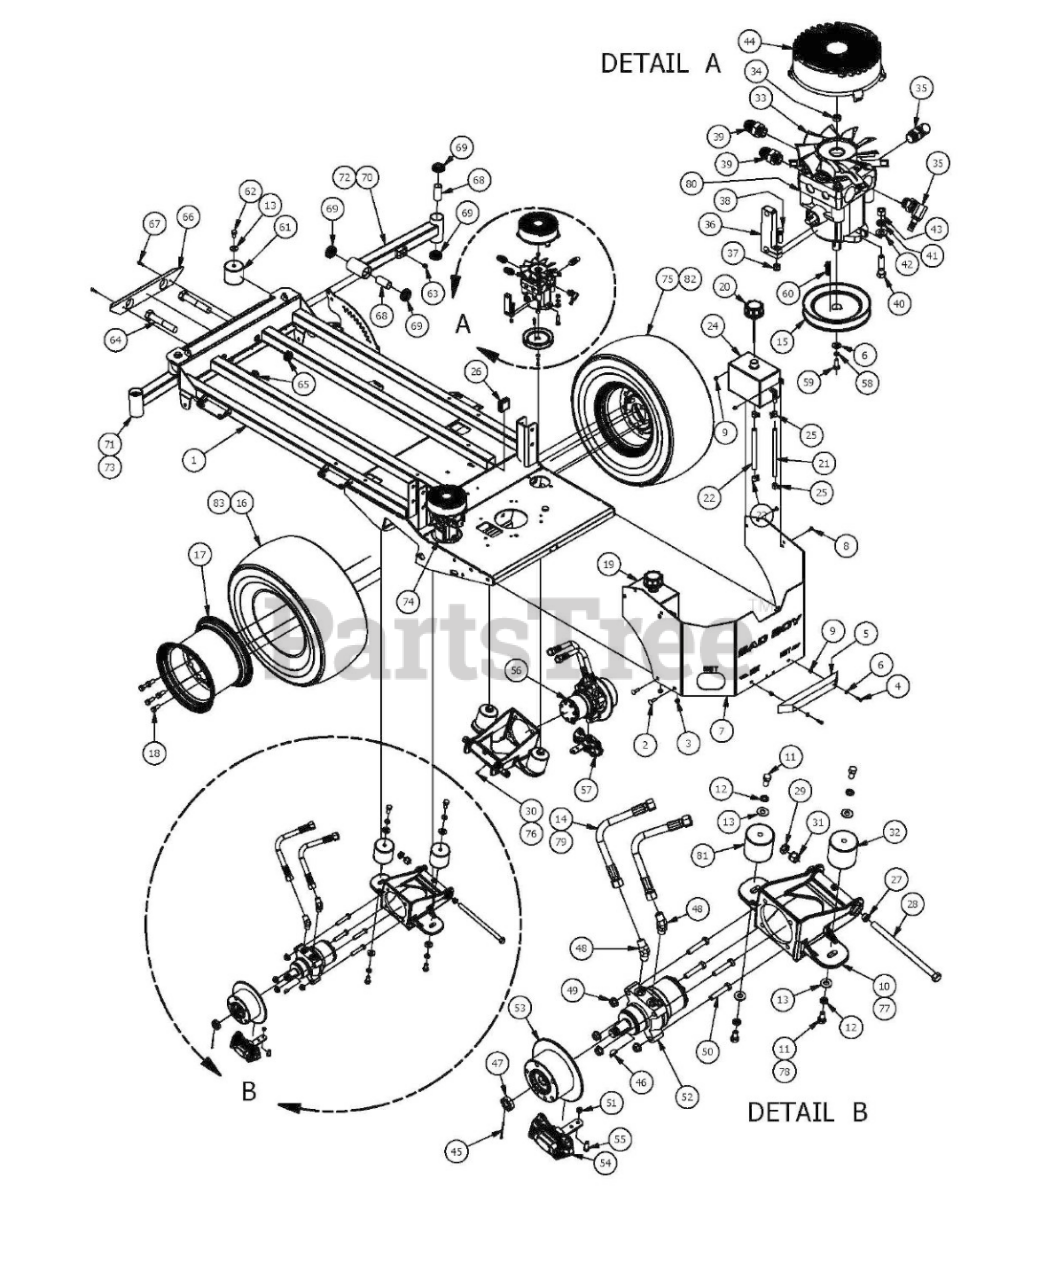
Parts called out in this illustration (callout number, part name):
1	2017 XP Frame
2	3/8" x 1 1/4" Carriage Bolt
3	3/8 Nylock Nut
4	1/4-20 x 1-1/4 GR 5 Hex Bolt
5	14" Rubber Bumper
6	1/4" Flat Washer
7	Outlaw Rear Plate
8	1/4" x 3/4" Carriage Bolt
9	1/4-20 Nylon Insert flange Nut
10	60 Suspension kit Wheel Motor
11	1/2" x 1" Hex Bolt
12	1/2" Lock Washer
13	1/2" Washer (Grade 8)
14	18" hose Assembly W/forged 45 Degr
15	5" Pump Pulley
16	24 x 12-12 Tire Pro Maxxis
17	12x12" Black Wheel For 2015 Outlaw
18	1/2-20 x 1-1/2 Lug Bolts Zinc
19	Outlaw Hydraulic Tank Left
20	Hydraulic Tank Cap W/Dipstick
21	3/8" Clear Hose
22	1/2 Clear Braded Hose Priced/Foot
23	1/2 Hose Clamp
24	Outlaw Hydraulic Tank Right
25	3/8" Hose Clamp
26	2X2 Frame Plug
27	Flange Bushing for Deck Arm - Upper
28	5/8"x10" Hex Bolt (Grades)
29	5/8" Nylock (1/2 Jam)
30	1/4" Drive in Grease Fitting (72" Suspension Kit
31	5/8 Std NC Nylock Nut
32	Vibration Mount-Green Dot
33	Hydraulic Fan
35	3/8" X 9/16"-18 ORB Male Fitting (S,A-2 P-4)
37	1/4" Nylock Nut
38	1/4-20 x 1 GR 5 hex bolt zinc
39	Hydraulic Pump Fitting 6400-10
40	3/8" x 1 1/2" Hex Bolt
41	3/8" Lock Washer
42	3/8" Flat Washer
43	3/8" Hex Nut
44	Fan Guard 6" Fits wheel Motor Pumps
45	1/8x2-1/4 cotter pin Zinc
46	Woodruff Key
47	1" Castle Nut for Wheel Motor
48	45 Degree Fitting 31704-10-10
49	1/2" Flange Nut
50	1/2" x 2 1/2" Hex Bolt
51	5/16-18 Nylock Insert Locknut
52	15cc Parker Wheel Motor- Left
53	Brake Disk
54	XP/AOS Left Brake Caliper
55	3/8" x 1" Hex Bolt
56	15cc Parker Wheel Motor- Right
57	XP/AOS Right Brake Caliper
58	1/4" Lock Washer
59	M6-1.0 X 16MM Hex Bolt
60	5MM X 1 Square Key Stock
61	Vibration Mount- Red Dot
62	1/2" x 3/4" Hex Bolt
63	5/8 Round Insert
64	1-14 x 5.5 Hex Bolt Grade 8 Zinc Yellow
65	1" Fine Thread Nut
66	2017 XP Bumper
67	1/4 x 1 Hex Head Tek screw
68	2016 Front Bearing Spacer
69	Caster Bearing 2016 - 1641 Bearing
70	2017 XP Suspension Arm - Right
71	2017 XP Arm Assembly - Left
72	2017 XP Arm Assembly - Right
73	2017 XP Suspension Arm-Left
74	Left Pump 12cc
75	24 x 12 -12 Tire and Black Wheel Assembly
76	3/8" Threaded Grease Fitting (60" Suspension Kit Wheel Moter)
77	72" Suspension Kit Wheel Motor
78	1/2-13 x 1 1/4 Hex Bolt (Only on 60" Suspension
79	Kit Wheel Motor)
80	Right Pump 12cc
81	Vibration Mount-Blue Dot
82	2017 Outlaw Reaper Turf Wheel and Tire Assembly 24x12-12
83	2017 Outlaw 24x12-12 Reaper Tire
